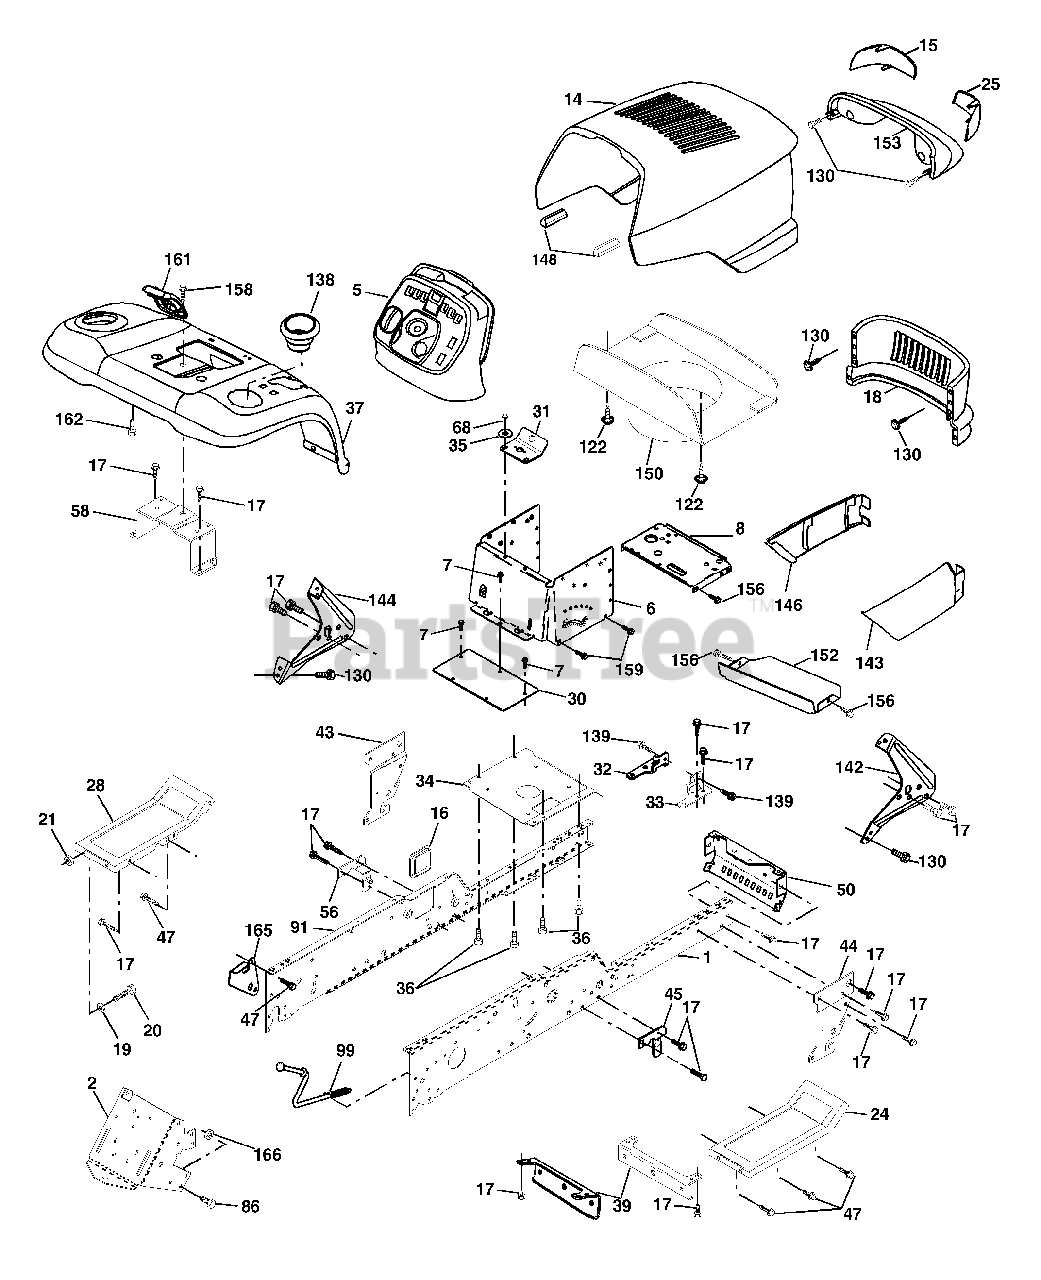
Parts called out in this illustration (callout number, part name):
1	Rail, Kit RH
2	Drawbar, Gt
5	Dash, Plastic
6	Dash, 1PCS, Lower
7	Screw, Thd Cut 1/4-20 x 1/2
8	Support, Battery
14	Hood Asm., Pnt
15	Lens LH
16	Cover, Access
17	Screw, 3/8-16 x 3/4
18	Grille
19	Washer 13/32 x 13/16 x 12 Ga.
20	Bolt, Fin Hex 3/8-16 x 1 Gr.5
21	Nut Lock Hex w/Ins 3/8-16 Unc
24	Footrest, RH
25	Lens RH
28	Footrest, LH
31	Bracket Supt 1-pc Vgt Steering
32	Bracket, Frame Pivot Lh
33	Bracket, Frame Pivot Rh
34	Plate Asm Engine Chassis
35	Washer 11/32 x 11/16 x 16 Ga.
36	Screw 5/16-18 x 3/4
37	Fender, Pnt.
39	Bracket, Axle Front
43	Bracket, Spnsn Front Lh
44	Bracket, Spnsn Front Rh
45	Bracket Asm., Susp Chassis Rh
47	Screw Thdrol 3/8-16 x 1/2
50	Bracket, Chassis Front
56	Bracket Asm., Susp Chassis Lh
58	Bracket Asm., Fender
68	Screw, 5/16-18 x 1/2
86	Bolt Hex 7/16-14 x 1 1/4 Gr. 5
91	Rail, Kit Lh
99	Rod Asm. Bypass
122	Screw Hex WSHD 8-18 x 7/8
130	Screw Hw Hd Hi-Lo #13-16 x 3/4
138	Cupholder
139	Bolt Shoulder 5/16-18
142	Bracket Dash Stealth RH
143	Skirt Grille RH
144	Bracket Dash Stealth LH
146	Skirt Grille LH
148	Extrusion Bumper
150	Duct Heat Hood
152	Shield, Browning
153	Light Box Asm w/Lens
156	Screw 5/16-18 x 3/4
158	Screw 3/8-16 x 1/2
159	Screw Hexwsh THDR 3/8-16 x 3/4
161	Consol Fuel Window
162	Screw Hex Wsh Hi-Lo 1/4-1/2 Unc
165	Bracket Support Tank
166	Nut, Lock Hex 7/16 Unc
